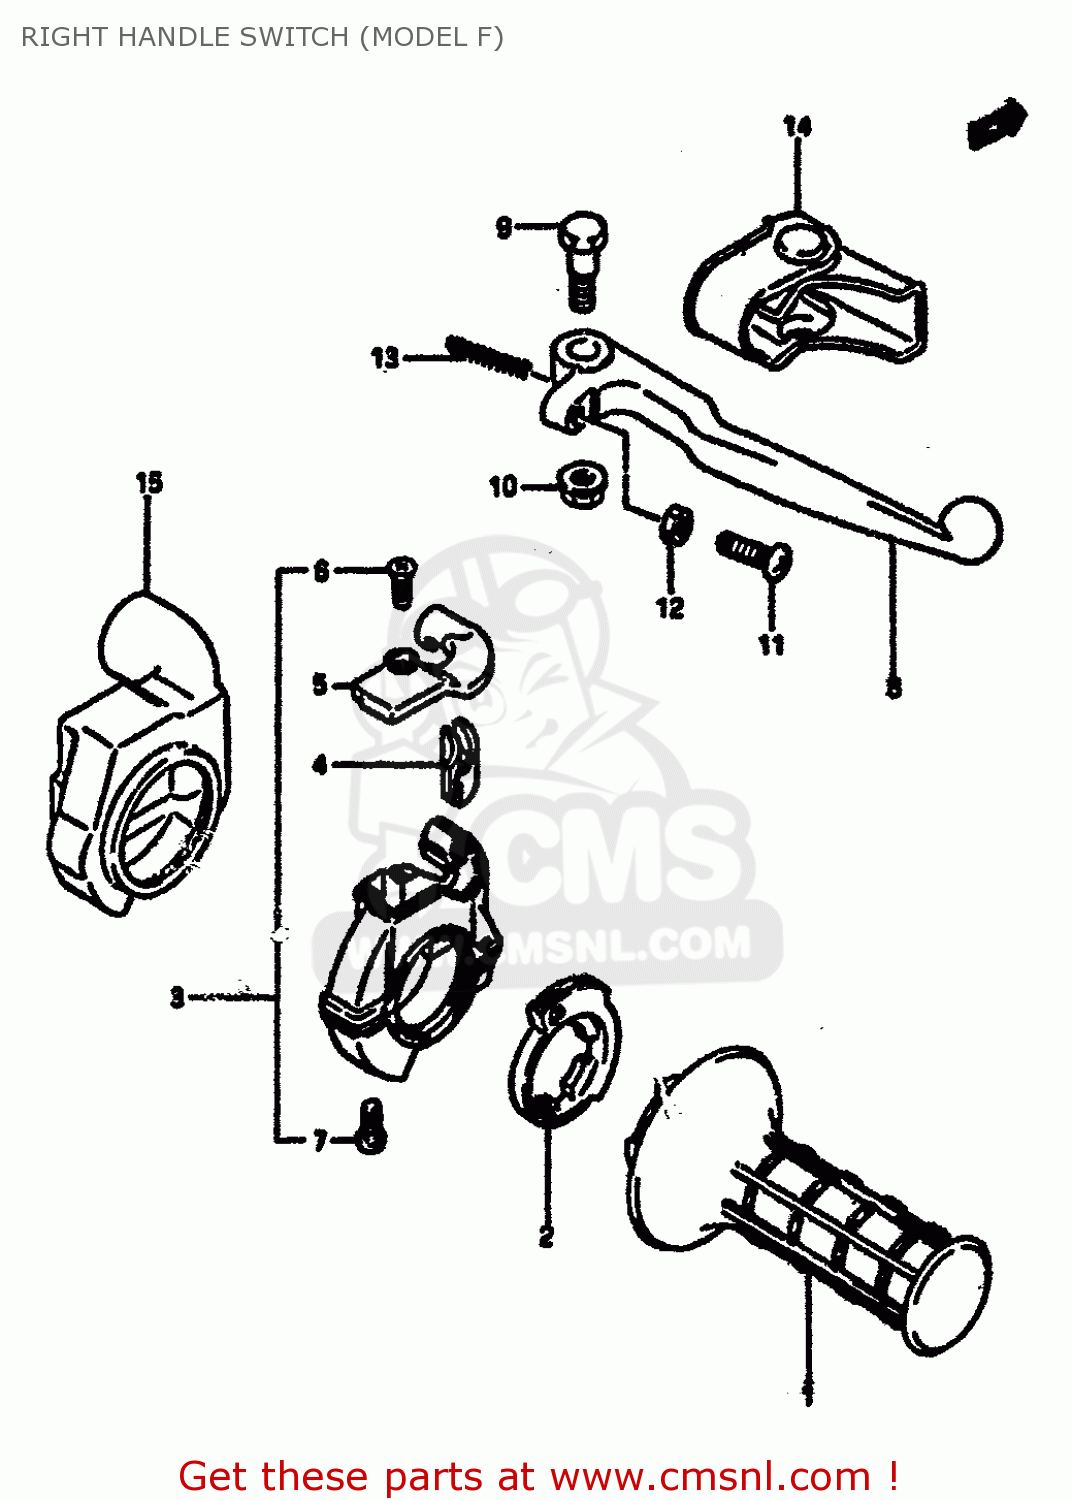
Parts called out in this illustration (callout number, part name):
1	GRIP,THROTTLE
2	ROTOR,THROTTLE GRIP
3	CASE ASSY,THROTTLE
4	GUIDE PIECE,THROTTLE
5	COVER,THROTTLE CASE
6	SCREW
7	SCREW
8	LEVER,BRAKE
9	BOLT,BRAKE LEVER
10	NUT,BRAKE LEVER
11	BOLT,LEVER
12	NUT ,5MM
13	SPRING,RETURN
14	COVER,BRAKE LEVER
15	COVER,THROTTLE CASE
